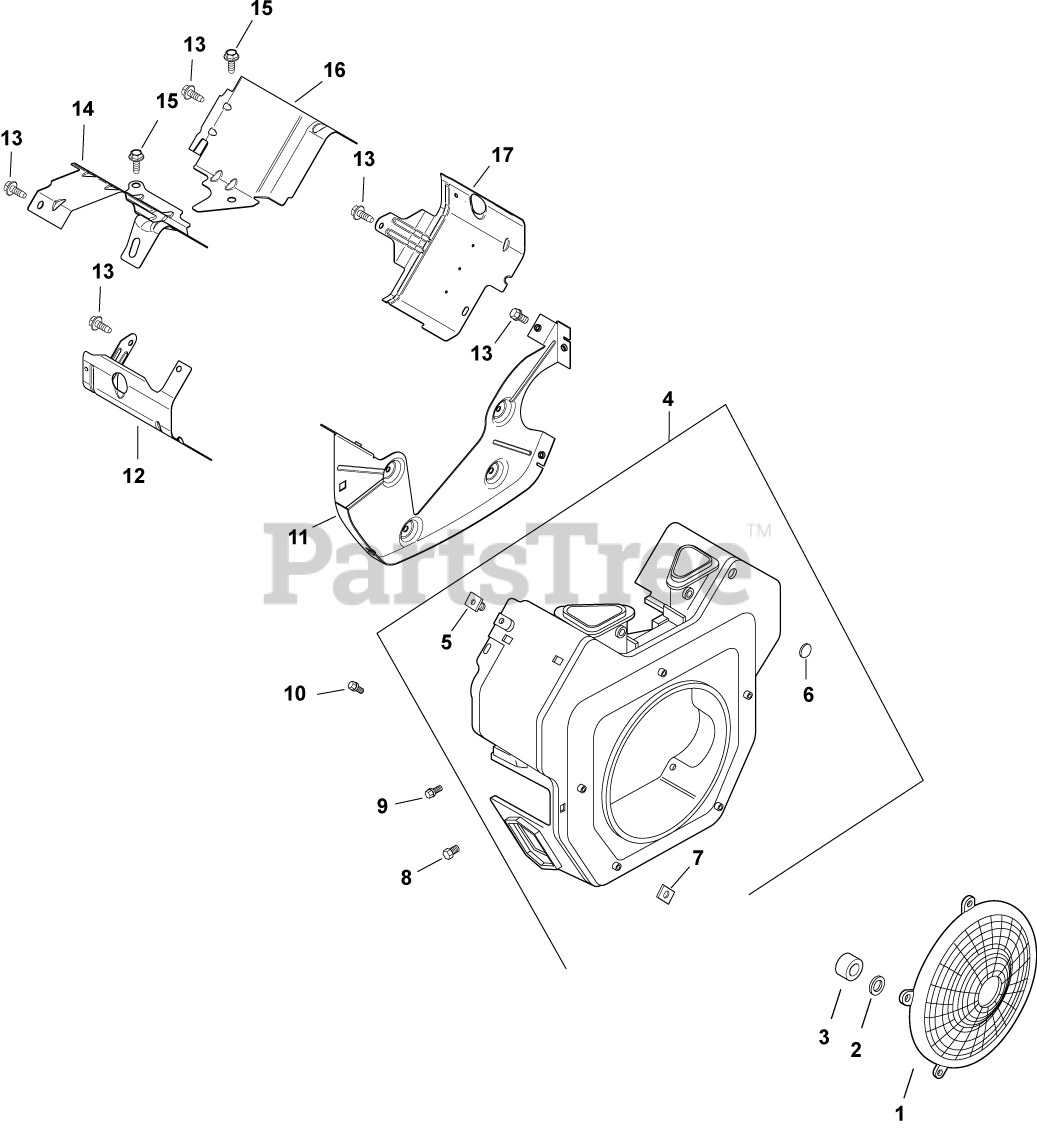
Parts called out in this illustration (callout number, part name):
2	WASHER, FLAT 1/4" (O.D. 5/8")
3	SPACER USE 25 112 30-S
4	KIT, BLOWER HOUSING ASSEMBLY USE 24 027 488-S
5	NUT, PLASTIC
6	PLUG, BUTTON 9/16
7	NUT, PLASTIC (KM)-USE 25 100 37-S
8	SCREW - USE M-545016-S
9	SCREW,FLG THD FRM M5X0.8X16-(#25086398S)
10	SCREW, FLG THD FRM M5X.8X20-(#25086399S)
11	PLATE, BACKING-USE 24 146 59-S
12	KIT, CYL BAFFEL #2 SIDE
13	SCREW,FLG THD FRM M6X1.0X16-(#25086397S)
14	BAFFLE, VALLEY #2 SIDE-USE 24 063 94-S
15	SCREW, FLG THD FRM M5X.8X10
16	BAFFLE, VALLEY (CH)-USE 24 063 93-S
17	KIT, CYL BAFFEL #1 SIDE
